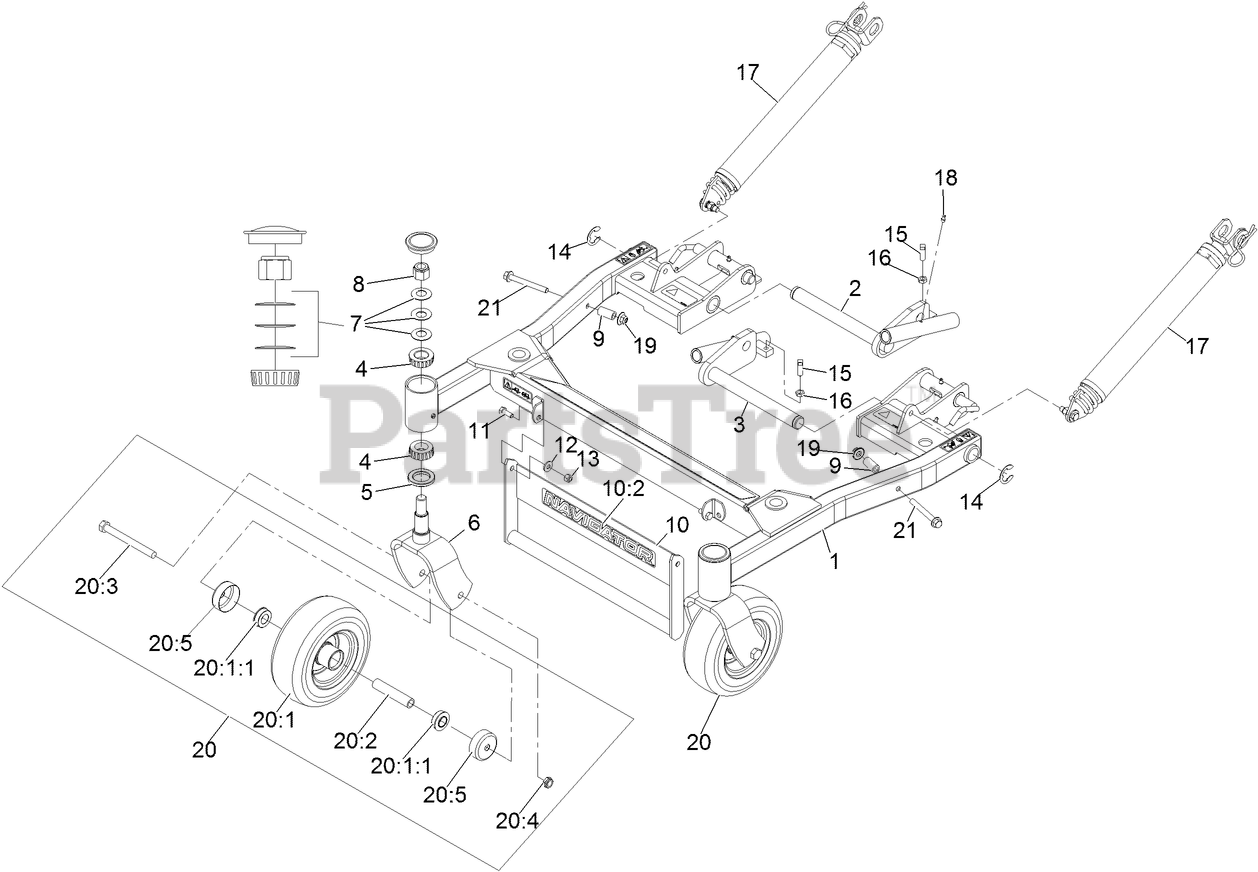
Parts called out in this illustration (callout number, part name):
1	Frame-Deck Support W/Decals
2	PIVOT-DECK, RH
3	PIVOT-DECK, LH
4	Cone-Bearing Tapered Roller
5	SEAL-GREASE
6	FORK-CASTER
7	WASHER-BELLVILLE
8	NUT-LOCK, NI
10	ASM,DECK LIFT HANDLE W/DECAL
10:2	DECAL-NAVIGATOR LOGO
11	SCREW-HH
12	WASHER-SPRING
13	NUT-LOCK, NI
14	RING-SNAP
15	SCREW-SET, SQH
16	NUT-JAM
17	LIFT ASSIST SPRING ASM
18	FITTING-GREASE
19	Nut-Nyloc 3/8-16 Flg
20	ASM,FF CASTER WHEEL W/AXLE
20:1	ASM,WHEEL AND TIRE
20:1:1	Bearing-Ball
20:2	SPACER-CASTER, FRONT
20:3	SCREW-HH
20:4	NUT-HEX
20:5	GUARD-SEAL
21	Screw-HHF
